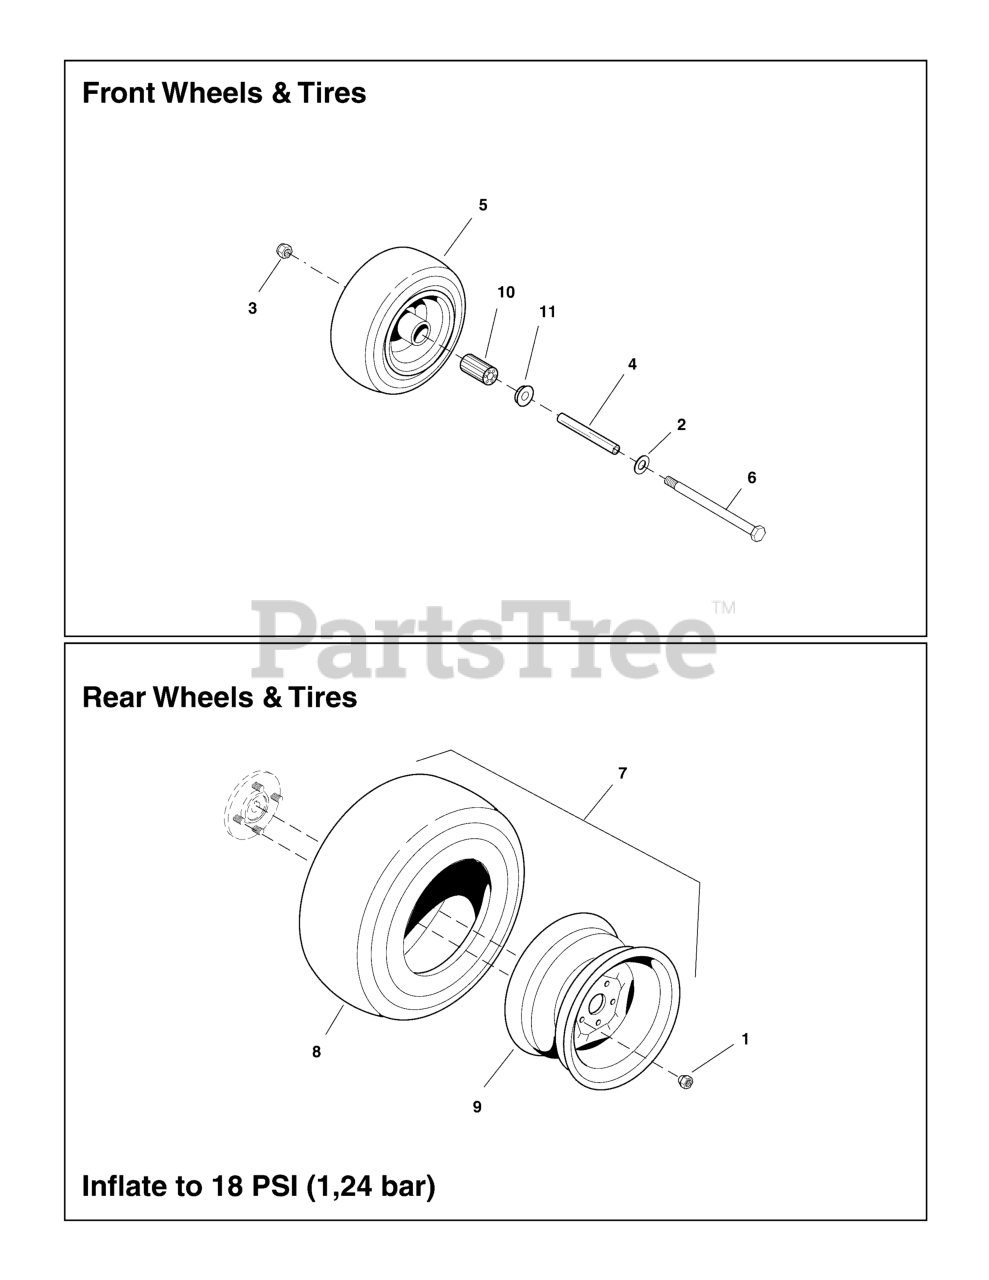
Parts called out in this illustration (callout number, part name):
1	NUT, 1/2-20, FOR WHEEL BOLT SILVER
2	WASHER, 1/2 SAE
3	NUT, Hex Flange, Nylock, 1/2-13
4	AXLE, Front Caster
5	TIRE/WHEEL ASSM 11/4.00-5 FLAT FREE
6	BOLT, HEX, 1/2-13 X 7, GD 8, YZ
7	TIRE/WHEEL ASM, 22X10.00 - 10 TURF MASTE
8	TIRE, 22 X 10 X 10, RUBBER
9	WHEEL, 10 X 7, 4/4 BC, 1.12" POS OFFSET
10	BEARING, CASTER WHEEL, 11 X 4.0 - 5 BEAD LOCK (SV)
11	RETAINER, BEARING (TWO PER TIRE)(SV)
